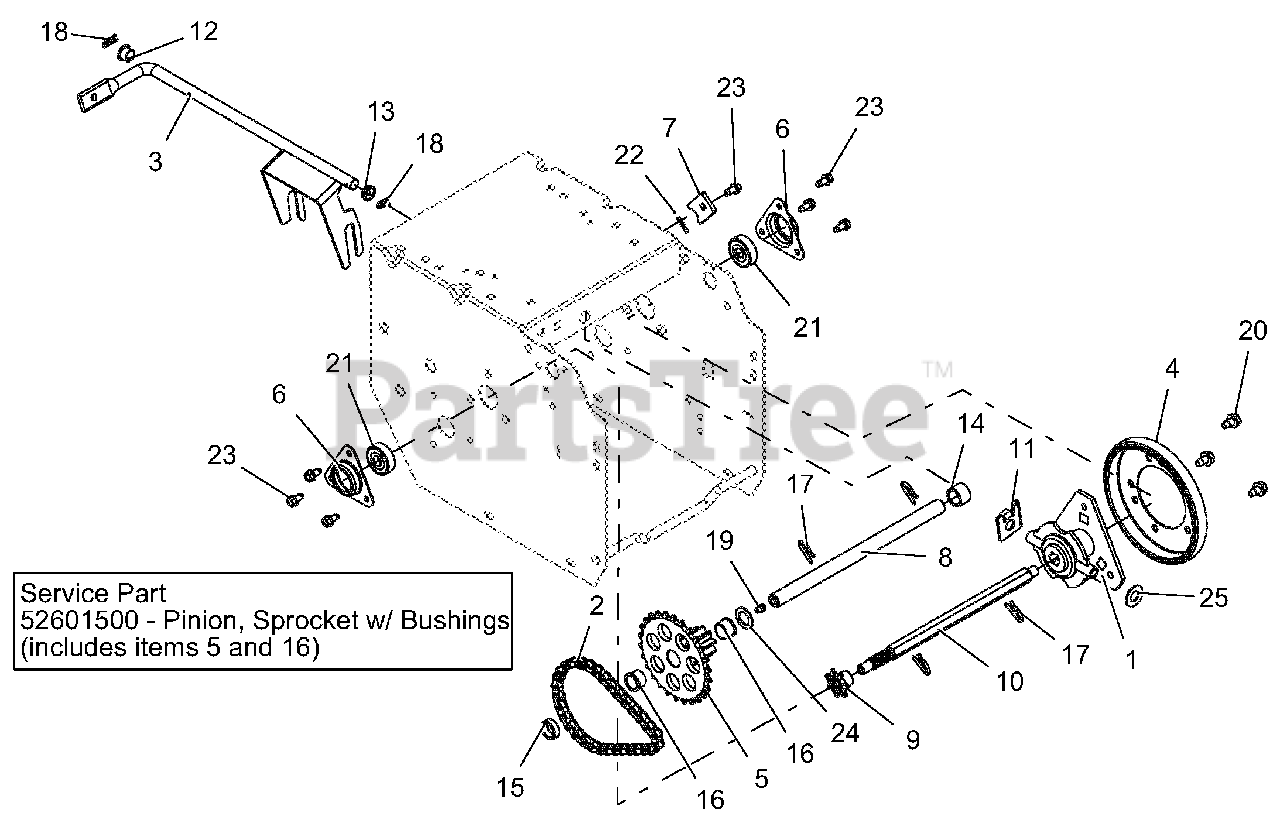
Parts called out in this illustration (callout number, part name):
1	CARRIER, DRIVE DISK
2	CHAIN - #41, 32 PITCHES
3	WELDMENT, SHIFT FORK
4	FRICTION, DISC
5	PINION & SPROCKET
6	FLANGE, BEARING
7	TAB, ANTI ROTATION
8	SHAFT, PINION
9	SPROCKET, PINION 7T W/SPLINE
10	SHAFT, HEX W/SPLINE
11	BRACKET, FORMED - SHIFT FORK
12	BUSHING, POLYLINER-.50 SPLIT
13	BUSHING, POLYLINER-.50 SNAPIN
14	SPACER, .635X.880X.611
15	BSHG-SLV, .635X.880X.305
16	BSHG-FLG .625X.750X.500X.875
17	PIN, SPRING CLIP
18	CLIP, SPRING
19	ZERK,FITTING .25X.125 DRIVE IN
20	@SCR-TAP .31-18X.50 HWH TR YWZ
21	BRG-BALL .437X1.375X.437
22	@PIN-GRV .125X1.00 TP E ALLOY
23	SCR-TAP .25-20X.50 HWH TR YWZ
24	WSHR-FL-STL .630X1.005X.062 YZ
25	WSHR-FL-STL .505X1.00X.062YWZC
26	PINION & SPROCKET W/BUSHINGS
